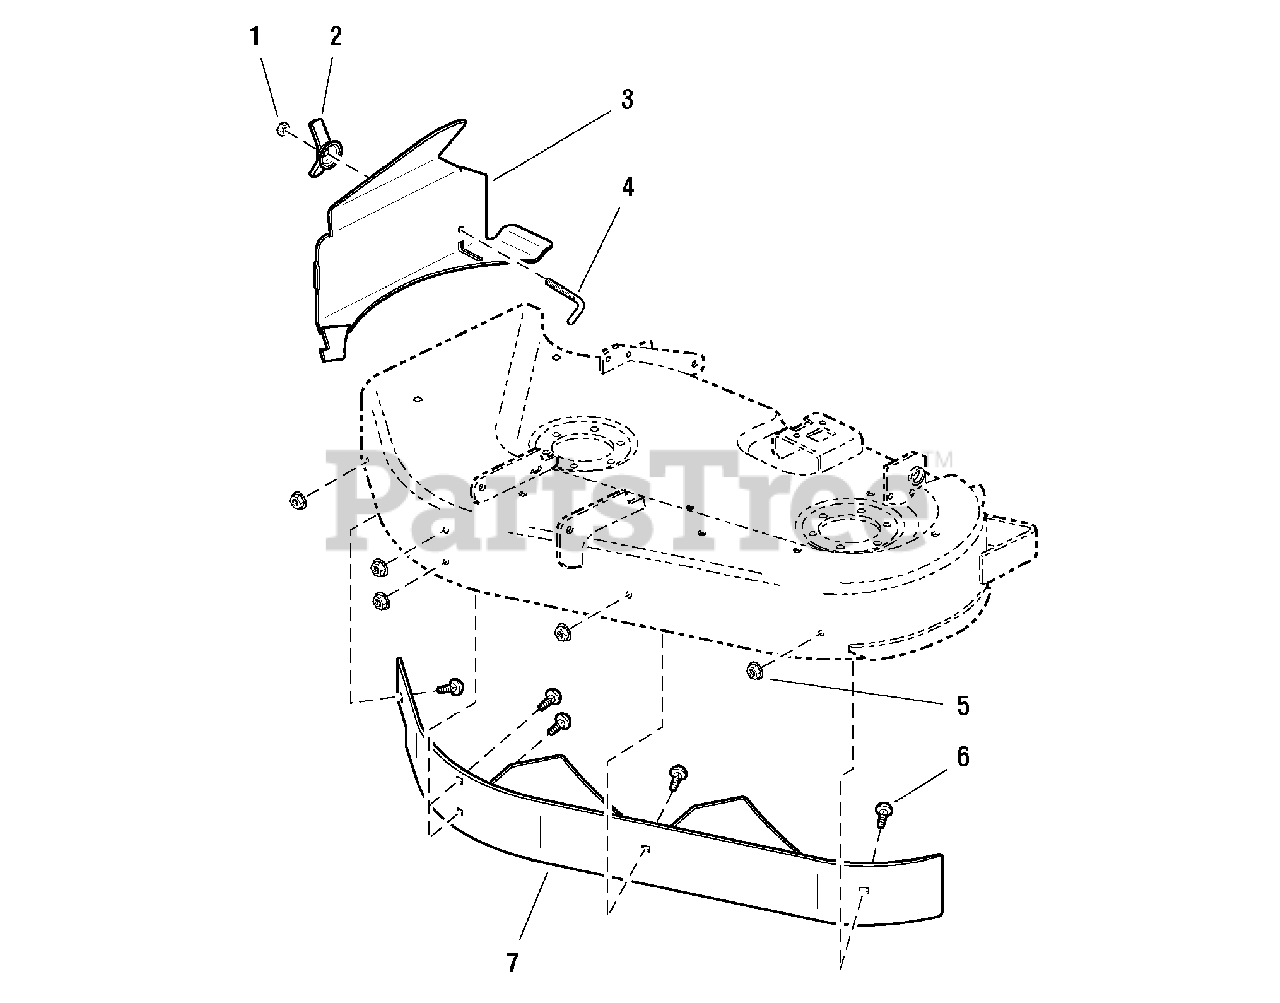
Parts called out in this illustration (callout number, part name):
1	NUT, Hex Lock, 5/16-18
3	MULCH PLATE
5	NUT, Hex Serrated Flange, 5/16-18
6	CARRIAGE BOLT, 5/16-18 x 3/4
7	BAFFLE ASSEMBLY, 34"
